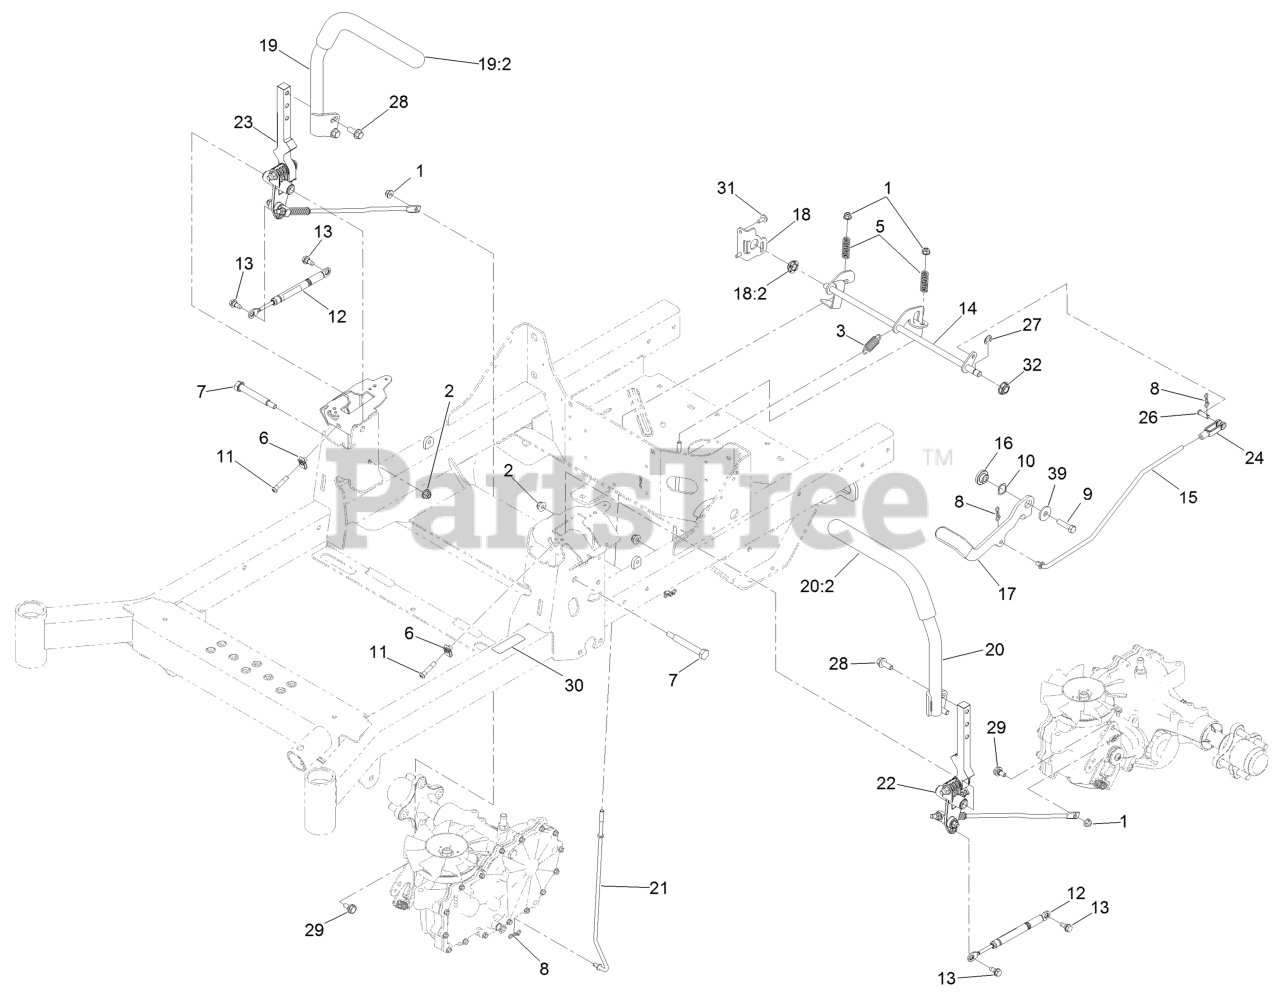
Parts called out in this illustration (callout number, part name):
1	Nut-Flange, NI
2	Nut-Flange, NI
3	Spring-Extension
5	Spring-Compression
7	Bolt-Pivot
8	Pin-Cotter, Locking
9	Screw-HH
10	Washer-Wave
11	Screw-HSBH
13	Screw-Shoulder,HHF,Thd Roll
14	Shaft-Brake
15	Linkage-Brake, Upper
16	Pivot-Flange
17	Lever-Brake With Grip
18	Bracket-Brake, W/Bushing
18:2	Bearing-Spherical
19	RH Control Handle ASM
20	LH Control Handle ASM
21	Linkage, Brake Lower
24	Yoke-Adjustable
26	Pin-Clevis
27	Ring-Retaining, External
28	Screw-HHF
29	Bolt-Shoulder
30	Decal-Brake, Parking
31	Screw-Torx
32	Bearing-Spherical
39	Washer
